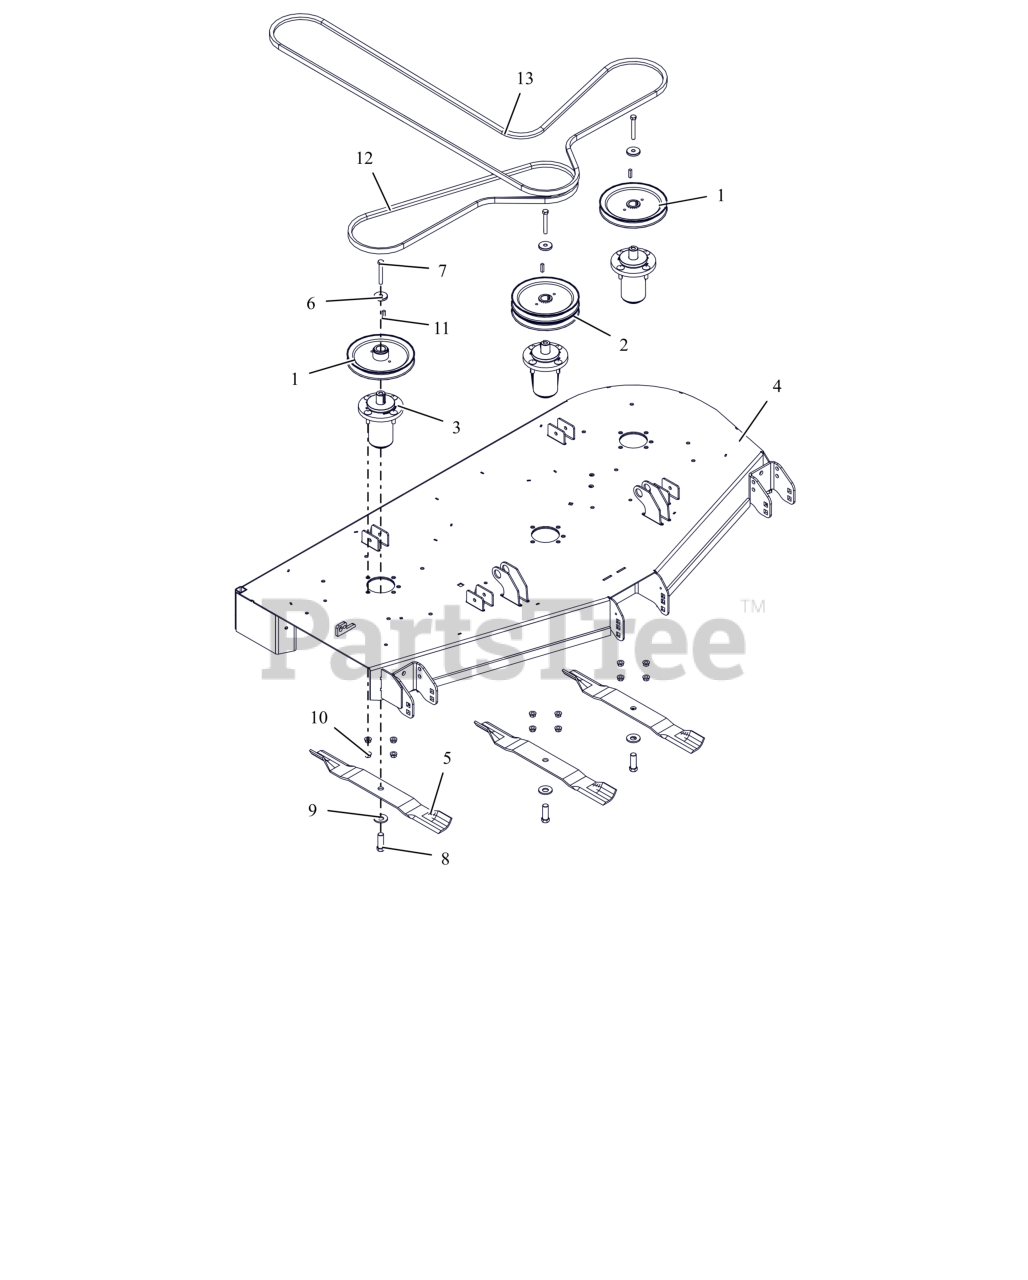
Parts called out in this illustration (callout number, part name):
1	PULLEY, V-7.50 OD X 1"ID
2	PULLEY, DOUBLE 1"X7.50"&7.50" (BLACK)
3	ASM, MAINT FREE ALUM SPINDLE
4	KIT,DECK-60" W/DECALS-ARIENS
5	BLADE, 20.5"
6	RETAINER, SHEAVE
7	BLT, HEX .38-16X2.75 G8 ZCC
8	BLT, HEX .62-18X1.75 G8 ZCC
9	WSHR-BLVL .669X1.535X.138
10	NUT-LK-CTR-FLG .375-16 GF ZCC
11	KEY, SQ .25X.25X1.00 RC 40-50
12	V-BELT, B-COGGED
13	V-BELT, HB SECTION
